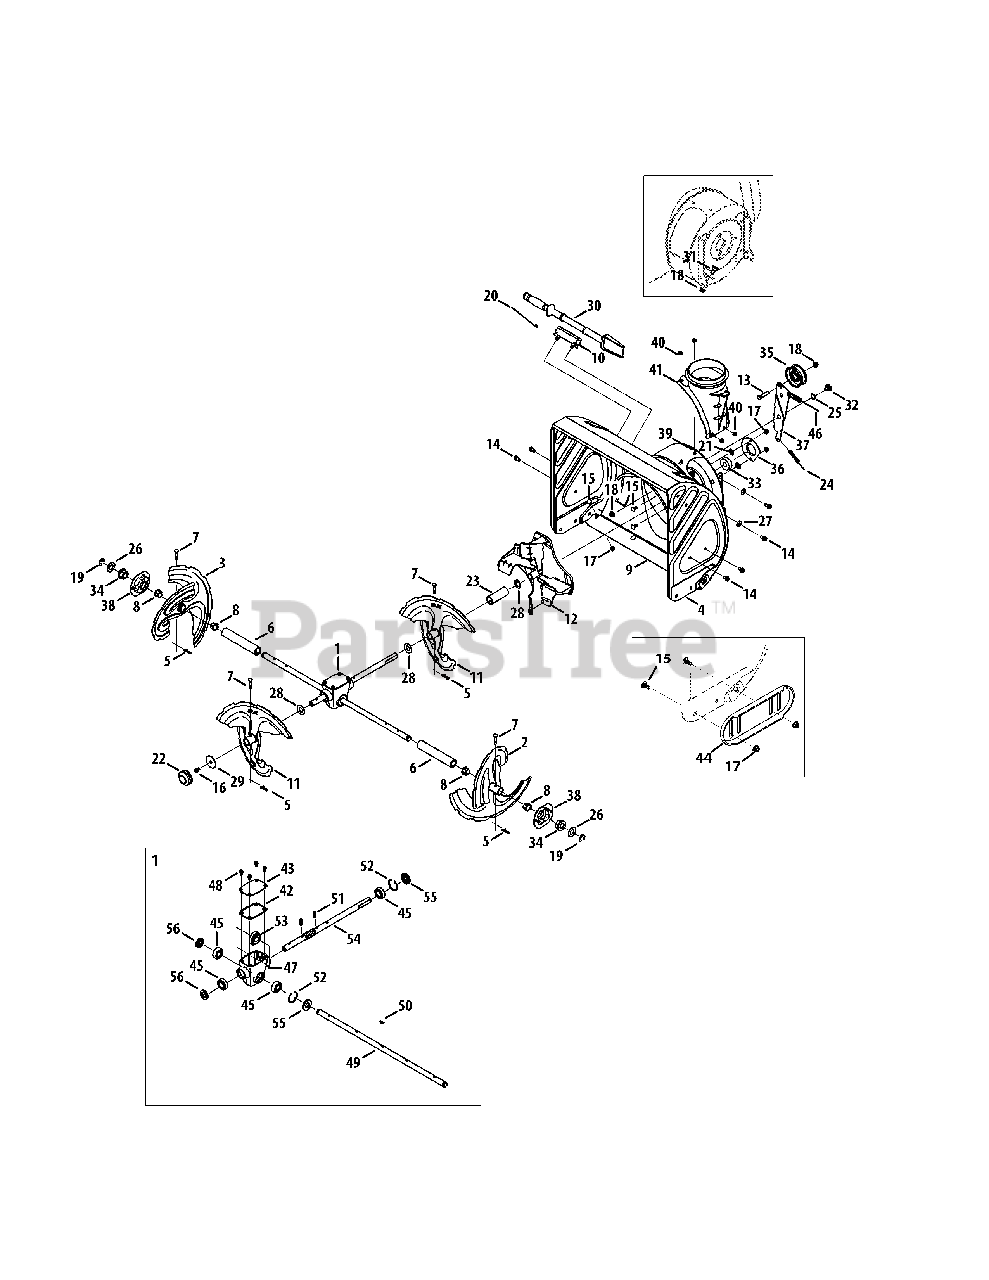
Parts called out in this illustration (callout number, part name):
1	Gearbox Assembly, Auger, 28"
2	Spiral Assembly - LH, 26" & 28"
3	Spiral Assembly - RH, 26" & 28"
4	Auger Housing, 28"
5	Bow Tie Cotter Pin
6	Spacer, 1.25 OD x .75 ID x 7.805 (28")
8	Flange Bushing, .800 x .910
9	Shave Plate, 28"
10	Clean-out Tool Mtg. Bracket
11	Accelerator Assembly
12	Impeller Assembly
13	Hex Bolt, 3/8-16 x 1.75
14	Screw, 5/16-18 x .750
15	Carriage Bolt, 5/16-18 x .750
16	Hex Washer Screw, 5/16-18 x .500
17	Flange Lock Nut, 5/16-18
18	Flange Lock Nut, 3/8-16
19	E-ring, .75
20	Cable Tie
21	Push-On Nut, .25 Dia.
23	Spacer, 1.35 OD x .76 ID x 2.705
24	Extension Spring, .38 OD x 4.59
25	Wave Washer, .625 x .885 x .0175
26	Flat Washer, .76 x 1.49 x .06
27	Bell Washer, .340 x .872 x .060
28	Flat Washer, .793 x 1.24 x .06
29	Flat Washer, .406 x 1.92 x .060
30	Clean-Out Tool
31	Shoulder Screw, 3/8-16 x .496 x .336
32	Shoulder Screw, 3/8-16 x .625 x .17
33	Flange Ball Bearing, .75 x 1.85
34	Hex Flange Bearing, .75 ID
35	Flat Idler Pulley
36	Bearing Housing
37	Auger Idler Bracket
38	Bearing Housing
39	Carriage Screw, 1/4-20 x 0.75
40	Flange Lock Nut, 1/4-20
41	Chute Adapter
42	Gearbox Gasket
43	Gearbox Cover
44	Deluxe Slide Shoe
45	Ball Bearing, .75 x 40 x 12
46	Auger Clutch Cable
47	Auger Housing
48	Screw, 1/4-20 x 0.75
49	Axle, Auger, 28"
50	Hi-Pro Key
51	Pin, Roll, .25 x 1.0
52	Retainer Ring
53	Worm Gear, 20T
55	Seal, .75 x 40mm x .25
56	Seal, .75 x 1.375 x .25
